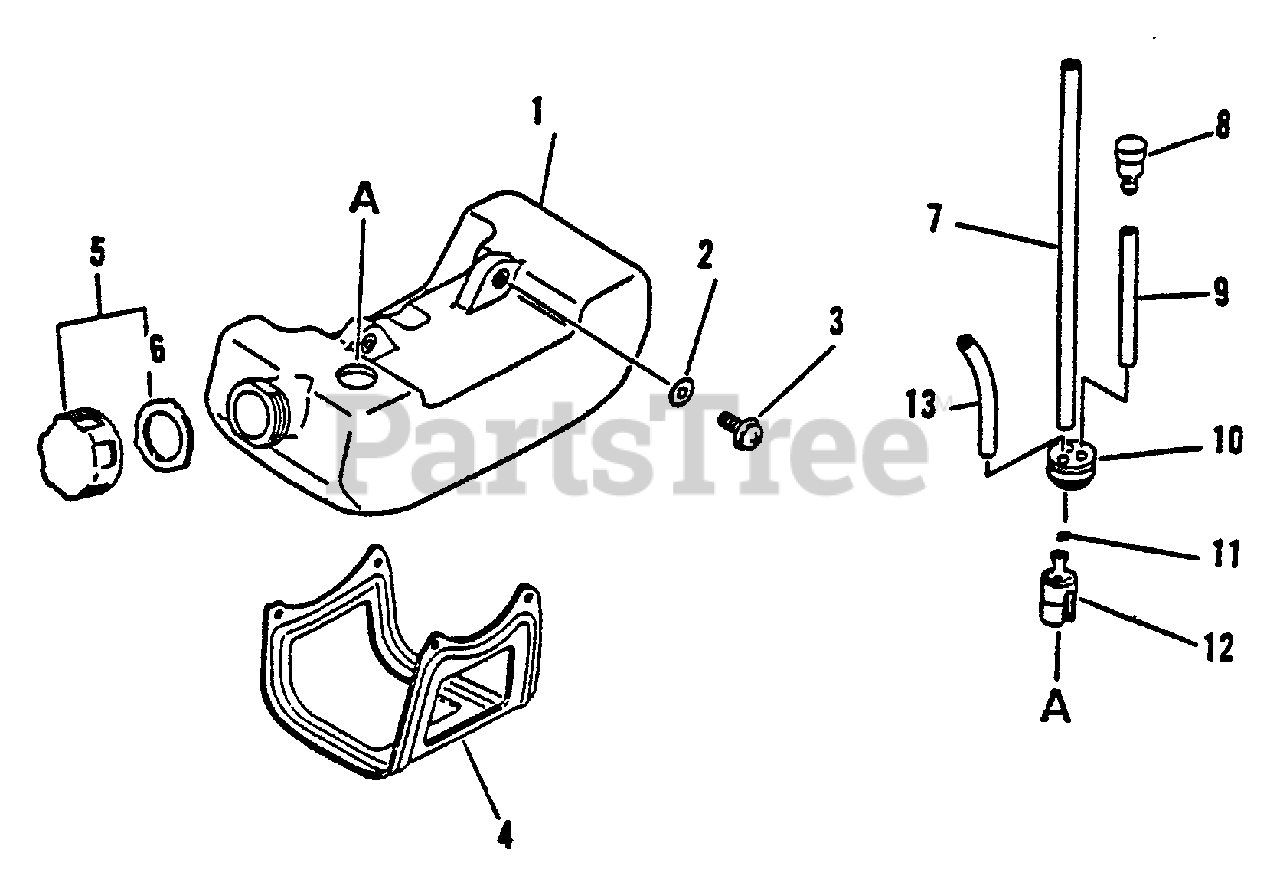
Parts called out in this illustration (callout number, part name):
1	TANK, FUEL
2	WASHER - 5
3	SCREW - 5X16
4	GUARD, FUEL TANK
5	CAP ASSY
6	GASKET, CAP
7	PIPE - 3X5X180 -- BLACK
8	VENT, FUEL TANK
9	PIPE - 3X5X70 -- BLACK
10	GROMMET
11	CLIP - 6
12	FILTER, FUEL
13	PIPE - 3X6X80 -- CLEAR
